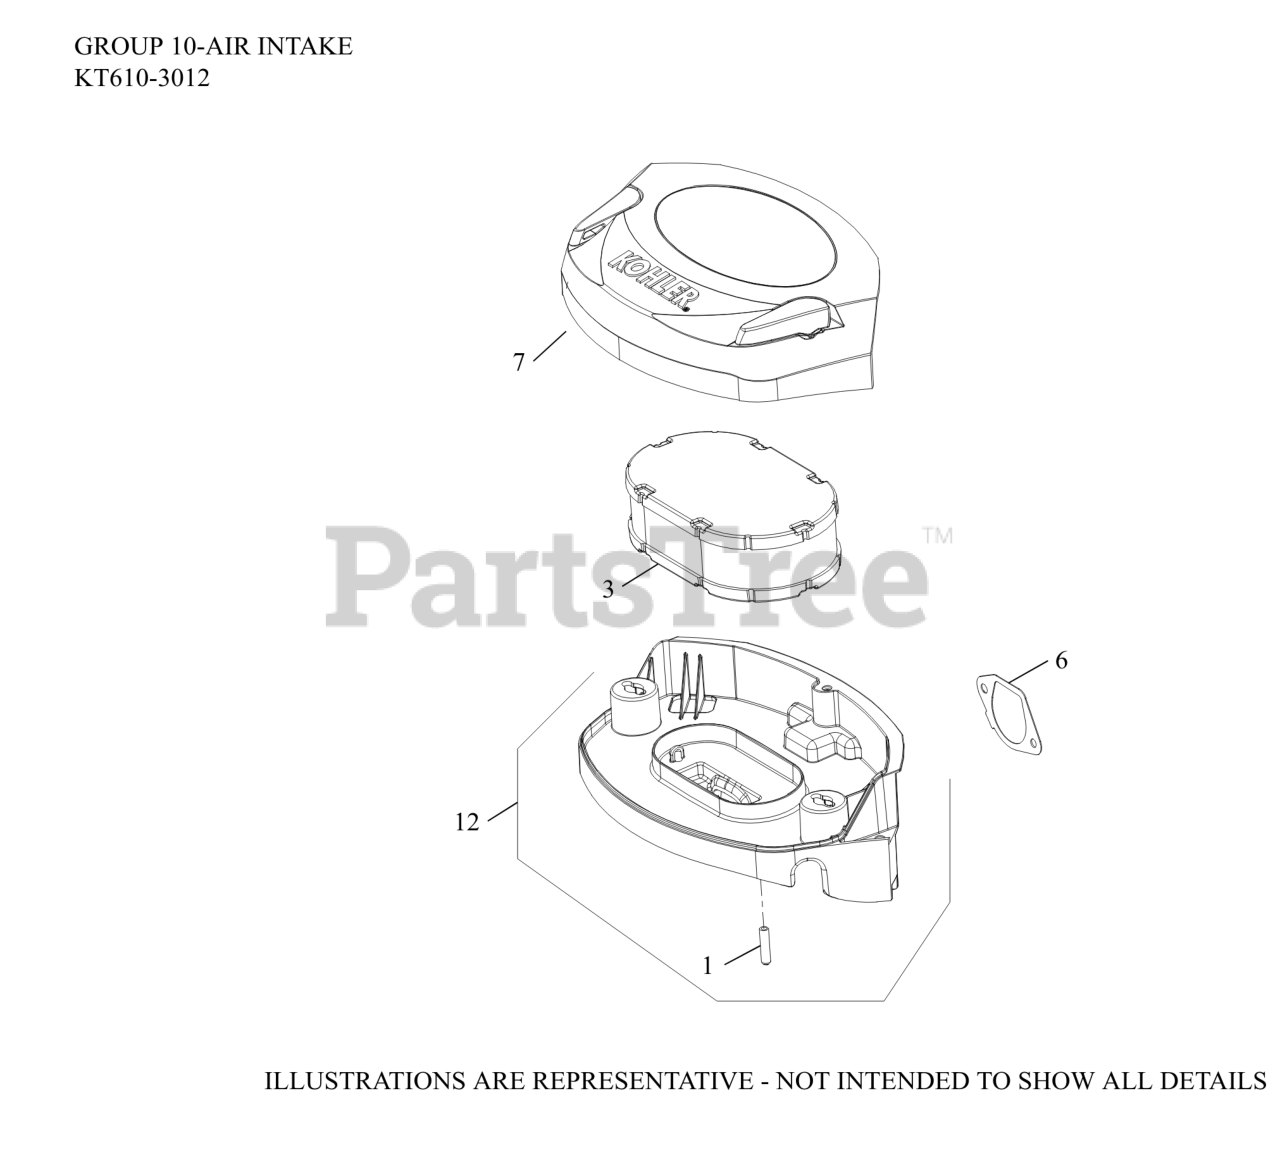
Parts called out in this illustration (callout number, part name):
1	CAP, MASKING
3	ELEMENT, AIR FILTER
6	GASKET, AIR CLEANER BASE
7	COVER ASSEMBLY, AIR CLEANER
12	BASE ASSY, AIR CLEANER
